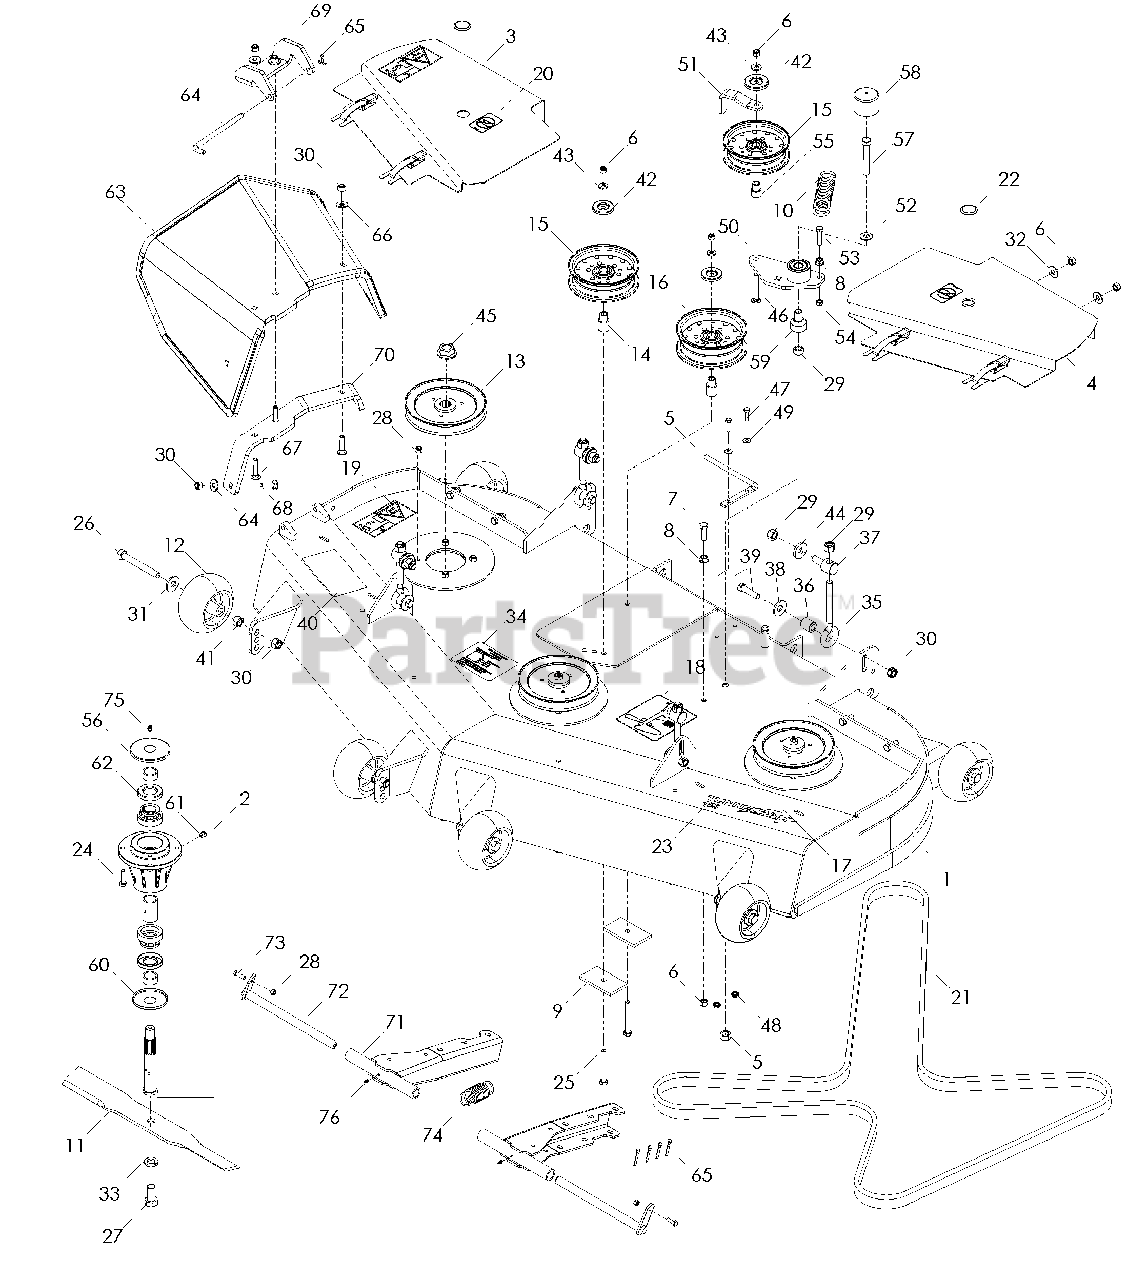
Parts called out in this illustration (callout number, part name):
1	61" Deck W/Decals
2	Housing Assm
3	Belt Shield 61" Rt
4	Belt Shield 61" Lt
5	Guide, Belt
6	Nut 3/8-16 Hex Nyloc
7	Hcs 3/8-16 X 1 1/4
8	Nut 3/8-16 Whizlk
9	Pad
11	Blade, 21"
12	Wheel, Gauge
13	Pulley, 61
14	Bushing, Idler
15	Pulley, Idler
16	Pulley, Idler (Wide)
17	Decal, Tunnelram 8"
18	Decal, Belt Routing
19	Decal, Severing
20	Decal, No Step
21	Belt, 61" Deck
22	Button Plug 1"
23	Decal, 155
24	Hcs 5/16-18 X 1 1/4
25	Hcs 3/8-16 X 3
26	Hcs 1/2-13 X 4
27	Hcs 5/8 X 1 1/4
28	Nut 5/16-18 Nyloc
29	Nut 1/2-13 Hex Nyloc
30	Nut 7/16-14 Ctrlk, Gr A
31	Washer 1/2
32	Washer 3/8
33	Washer 5/8 Slw
34	Decal, Anti-Scalp
38	Washer 1/2 Spring
39	Hcs 7/16-14 X 1 3/4
40	Decal, Discharge
41	Nut 1/2-13
42	Shield, Dust
43	Washer 3/8 Thick
45	Nut 3/4-16 Flanged
46	Rhsnb 3/8-16 X 2 3/4
47	Hcs 1/4-20 X 1
48	Nut 1/4-20 Hex Flanged
49	Washer 1/4 Flat Sae
50	Arm, Idler W/Bearings
51	Guide, Belt
52	Washer 1/2 Belleville
53	Hcs 3/8-16 X 1 1/2 Gr8
54	Nut 3/8-16 Jam
55	Bushing, Idler
56	Dust Cap, Top
57	Hcs 1/2-13 X 3 1/4
58	Cap, Vinyl
59	Pivot, Bearing
60	Dust Cap, Bottom
61	Poppet, Grease
62	Seal, Shaft
63	Discharge Chute
64	Pin, Chute Pivot
65	Pin, Cotter 1/8 X 3/4
66	Washer 5/16
67	Rhsnb 5/16-18 X 1 1/4
68	Rhsnb 5/16-18 X 1 1/2
69	Bracket, Chute
70	Reinforcement, Brcket
72	Pin, Pivot
73	Hcs 5/16-18 X 1
74	Spring, Extension
76	Zerk
